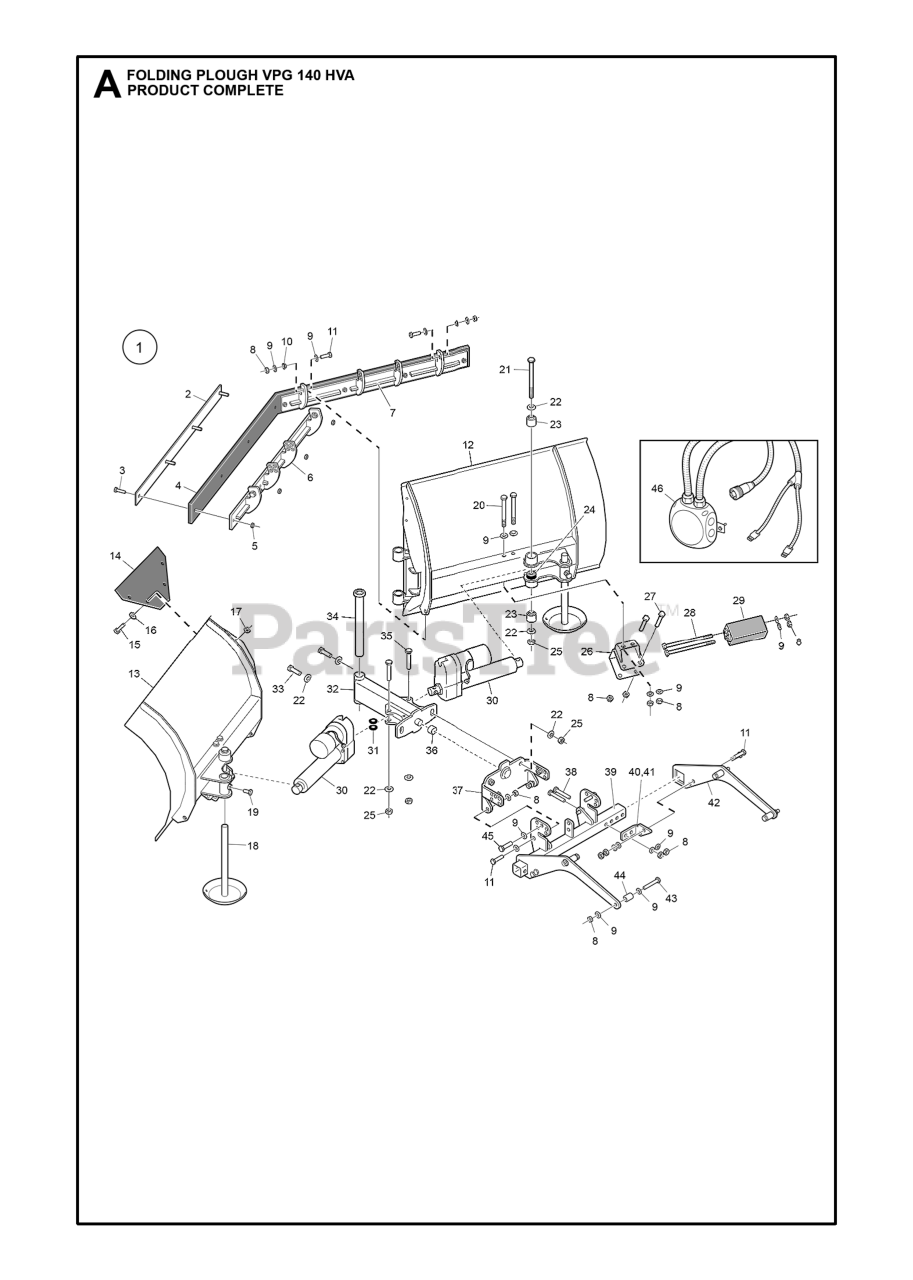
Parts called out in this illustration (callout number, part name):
8	NUT
9	WASHER
11	SCREW
15	Screw
17	LOCKNUT M6
22	WASHER - M12
25	LOCKNUT 12X1.75
45	REPL BY 725 25 00-71
